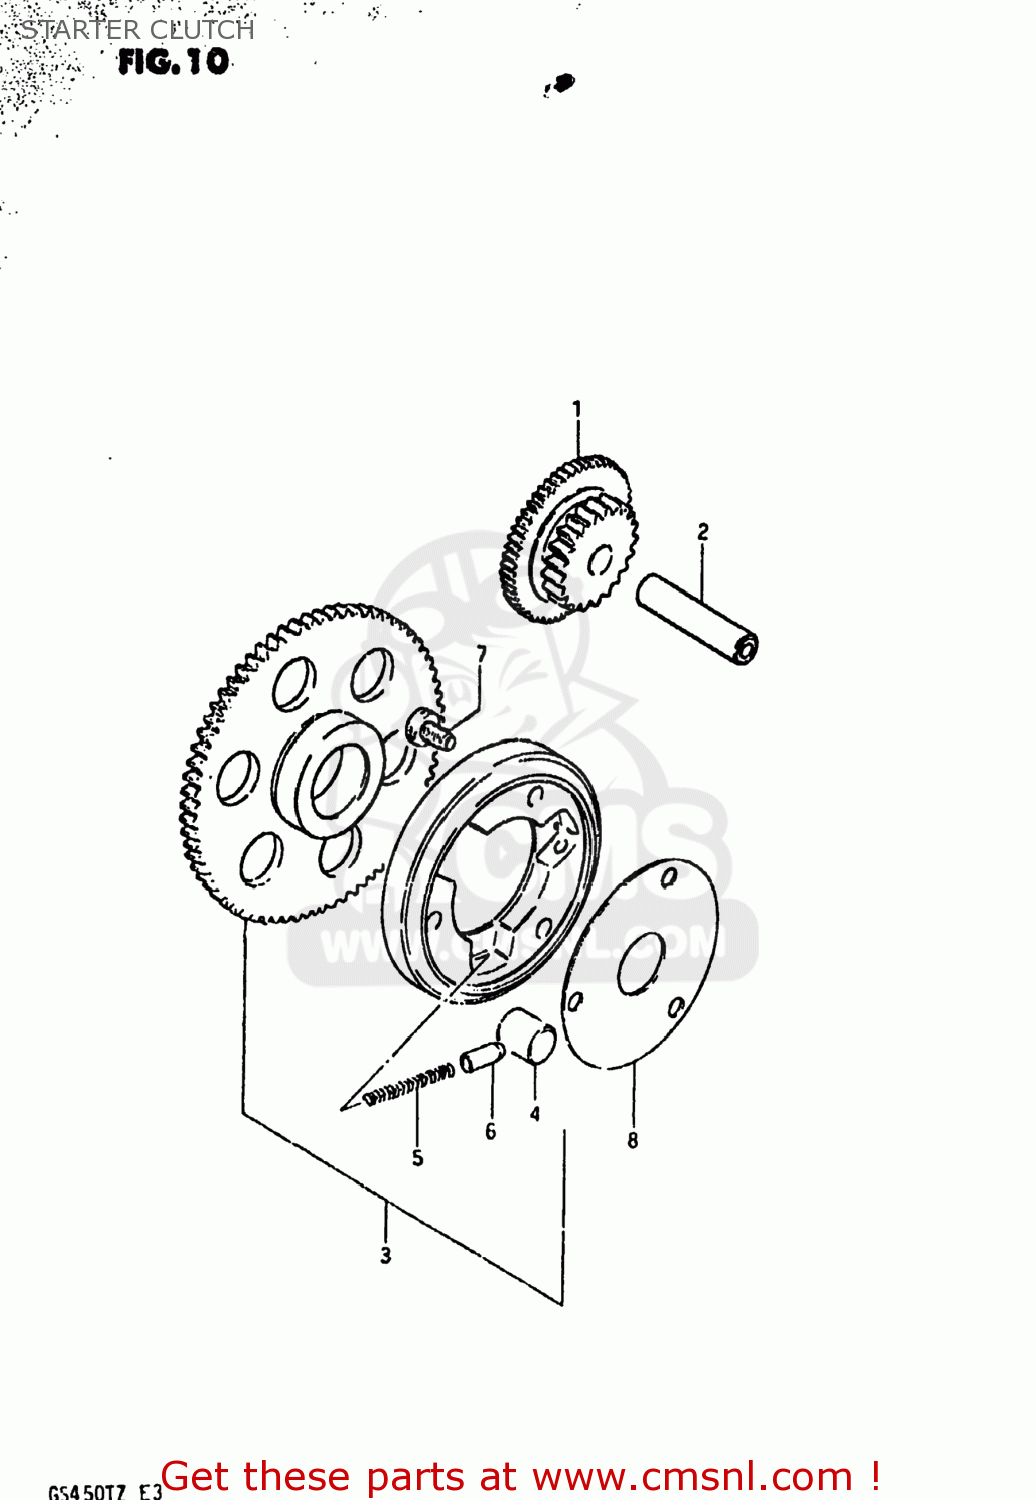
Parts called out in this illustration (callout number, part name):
1	GEAR,STARTER IDLE
2	PIN(7.4X13X56)
3	CLUTCH SET,STARTER
4	ROLLER(15X13)
5	SPRING
6	PIECE,PUSH
7	BOLT
8	SHIM,STARTER CLUTCH HUB
